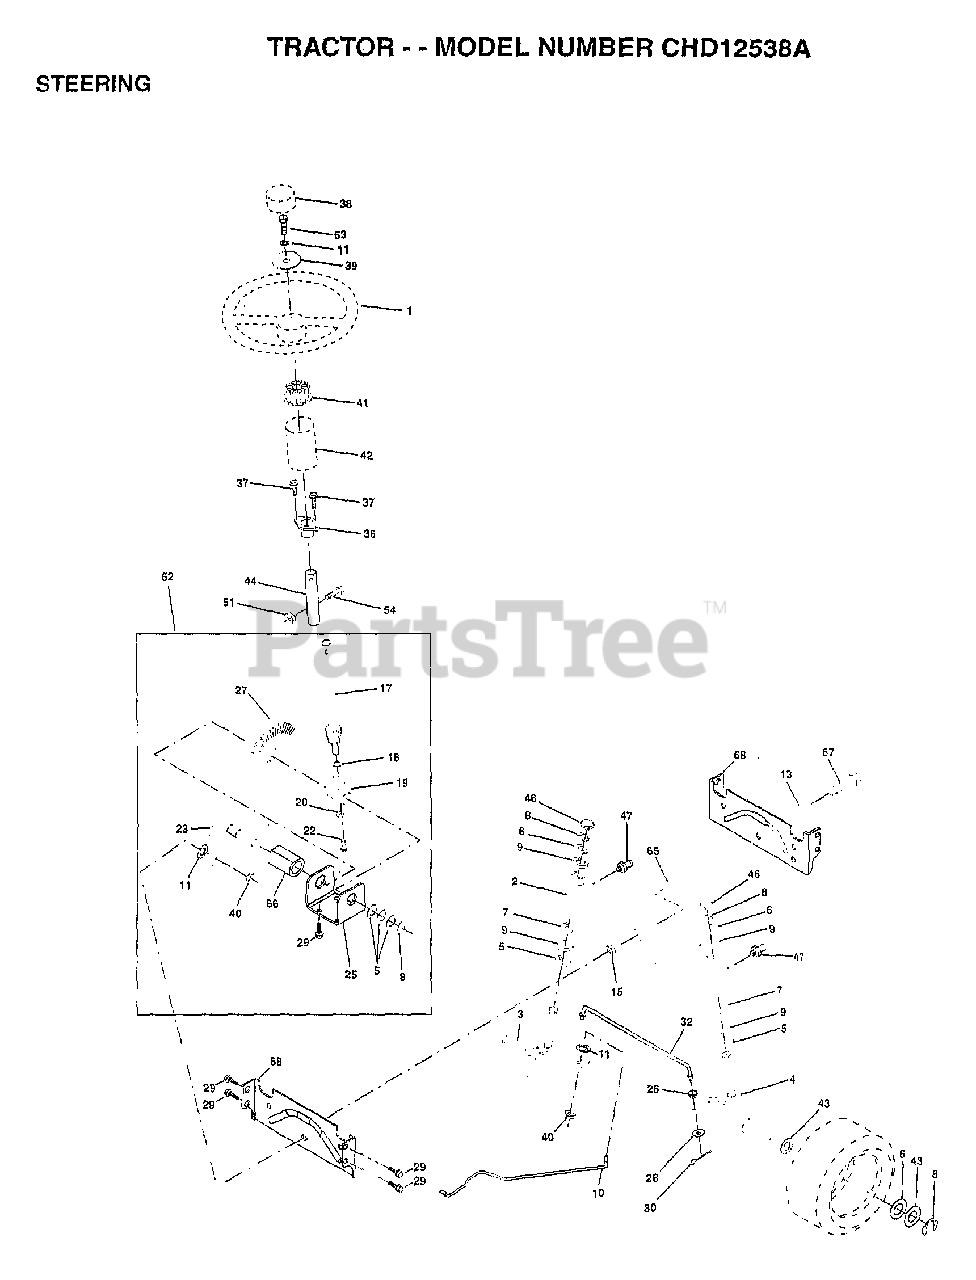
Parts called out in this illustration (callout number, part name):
1	WHEEL STR AYP BLK
2	AXLE ASM
3	SPINDLE.ASM.LH
4	"SPINDLE ASM,RH"
5	WASHER .T
6	WASHER
7	WASHER
8	RING
9	COL. SRTG. BEAR.
10	DRAGLINK-STAMPED
11	LOCKWASHER
13	BEARING AXLE
15	"NUT-LOC,FLANGE LT"
17	SHAFT ASM STEERIN
18	THRUST WASHER
19	SUPPORT.SHAFT
22	SCREW HEX SOC1/4-
25	BRKT-STEERING
26	BUSHING.DRAGLINK
27	GEAR SECTOR
28	WASHER
29	SCREW
30	COTTER PIN
32	TIE ROD
36	BUSHING.STEERING
37	"SCREW-TT,10-32 FL"
38	CAP STEER AYP
39	WASHER T
40	GRIPCO NUT
41	ADAPTER LT
42	BOOT.STEER.PL
43	WASHER
44	EXT SHAFT STEERIN
46	CAP
47	ZERK M
51	NUT
54	BOLT
62	KIT STEERING ASM
63	BOLT
65	SPACER AXLE
66	"BEARING-ARM,PITMA"
67	BOLT
68	BRACE AXLE
